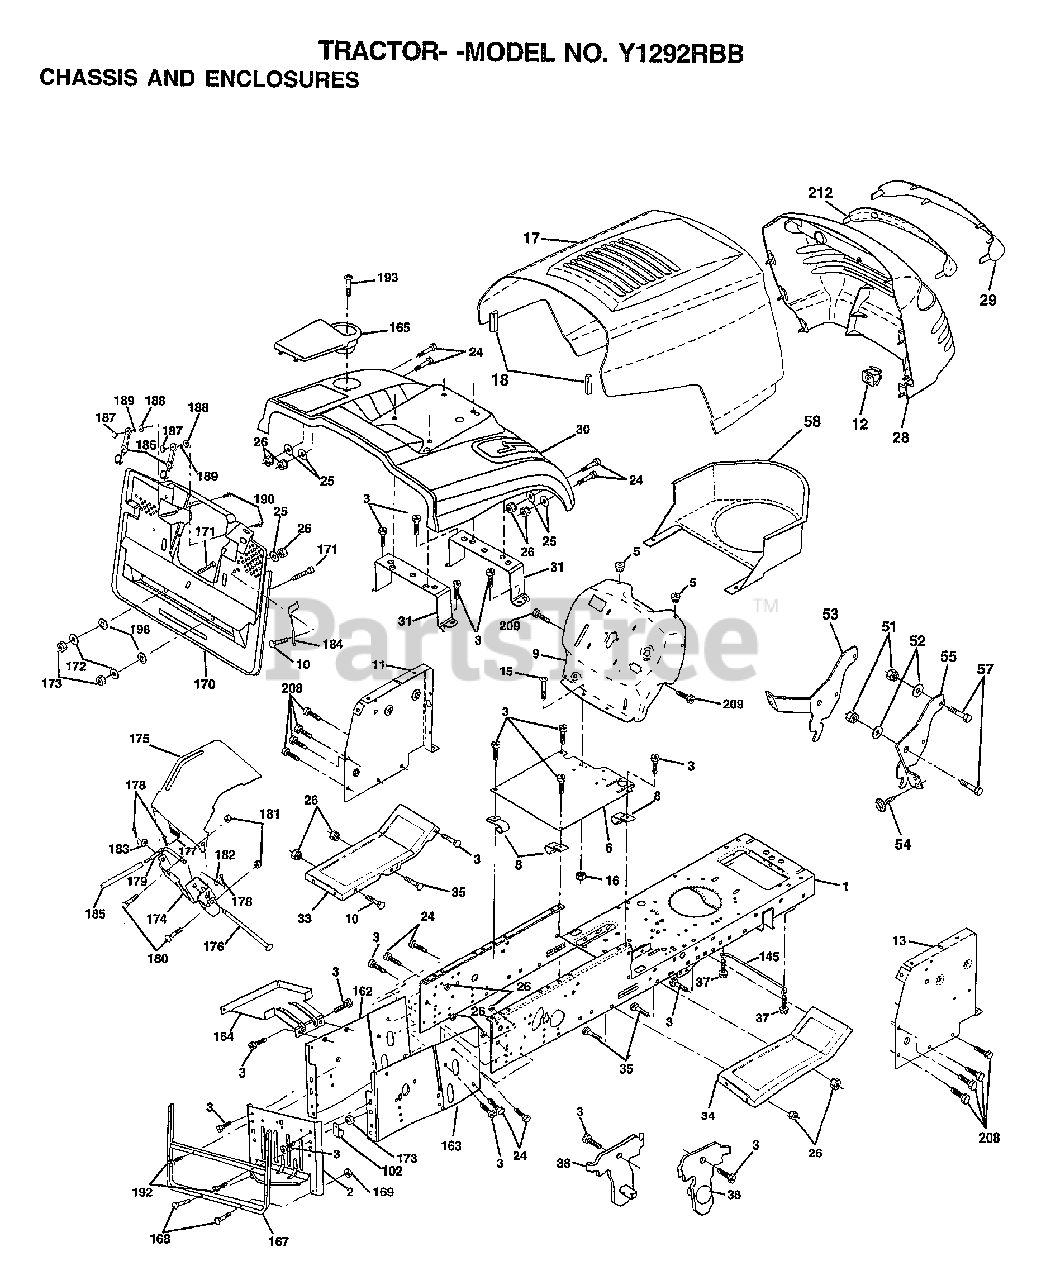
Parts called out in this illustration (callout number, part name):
2	DRAWBAR.CRD
3	SCREW
5	BUMPER-HOOD/DASH
6	SADDLE
8	"CLIP,INSULATOR"
9	DASH
11	"PANEL-DASH,LH"
12	CLIP.TINNERMAN
15	SCREW
17	HOOD.STEEL.ASSY
24	BOLT
25	WASHER
26	NUT
28	GRILLE-MS428
29	LENS.GRILLE.PRIVATE LABEL
30	FENDER.FEAR.CRD.RED
31	BRKT.SUPT.FENDER.CRD
33	FOOTREST.LH.LT/GT
34	FOOTREST.RH.LT/GT
35	BOLT
37	SCREW LT
38	BRKT ASM PIVOT MOWER REAR
51	NUT
52	WASHER
53	BRACKET.GRILLE.LH
54	SCREW.HEX.WS.HD
55	BRACKET.GRILLE.RH
58	AIR DUCT
102	CLIP T
145	"ROD POVOT,CHASSIS"
162	BRKT.EXT.CHASSIS.LH.CRD
163	BRKT.EXT.CHASSIS.RH.CRD
164	SUPPORT.BATTERY.CRD
165	COVER.BATTERY.CRD.BLACK.LT
167	SUPT.ASM.BACKPLATE
168	BOLT-RD HD SQ NK
170	COVER.BACKPLATE.BLACK
171	BOLT.HEX.3/8-16X2-1/2
173	NUT
174	BRKT.SWITCH.FBI.CRD
175	GRUARD.DOOR.REAR.CRD
176	HINGE PIN
177	SPRING.COVER.LH
179	ROD.PIVOT.FBI.CRD
182	WASHER.385X.625
183	WASHER
184	BRKT.ACTUATOR.BAG.CRD
185	TUBE.LEVER.SWCH.FBI.CRD
186	LATCH ASSY.BAGGER
187	WELDNUT
188	WASHER #10
189	LOCKWASHER
190	SCREW
192	SCREW LT
193	SCREW
198	NUT PUSH
208	SCREW
209	SCREW
212	INSERT LENS REFLECT
